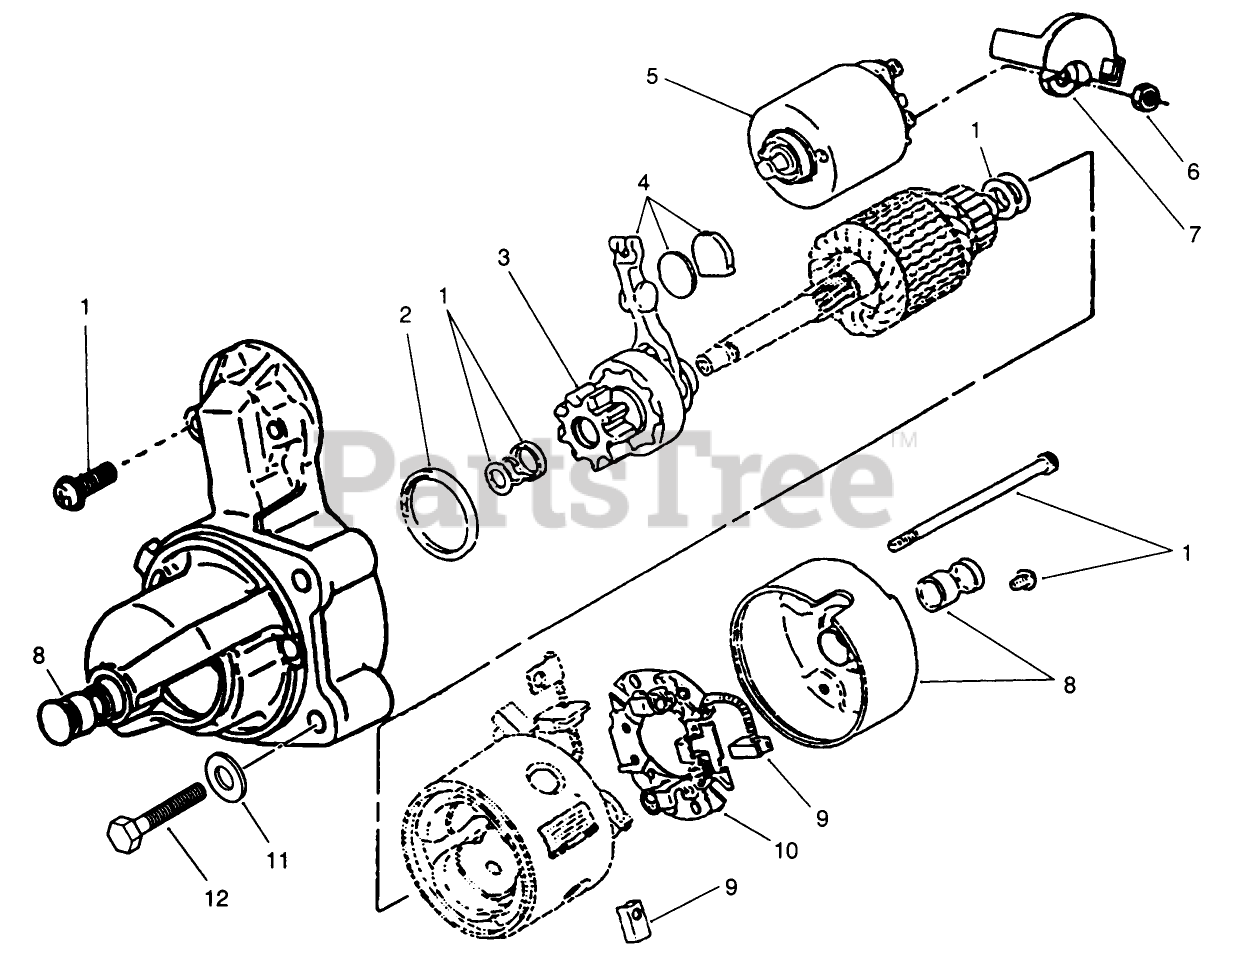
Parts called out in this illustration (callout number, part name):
1	Hardware Kit (Starter No. 191-1808-04)(Includes Solenoid Screws, Brush Holder Screws, Thru Bolts, Armature Shims, Pinion Stop Collar and Pinion Retaining Rings)
2	Dust Seal
3	CLUTCH STARTER ASSEMBLY
4	LEVER
5	STARTER SOLENOID KIT
6	Nut-Hex.
7	Cap-Starter Solenoid
8	Bushing Kit (Starter No. 191-1808-04) (Includes Rear Cap, Front & Rear Bushings)
9	BRUSH KIT
10	Brush Mounting Kit
11	WASHER
12	Screw-Hex Hd
